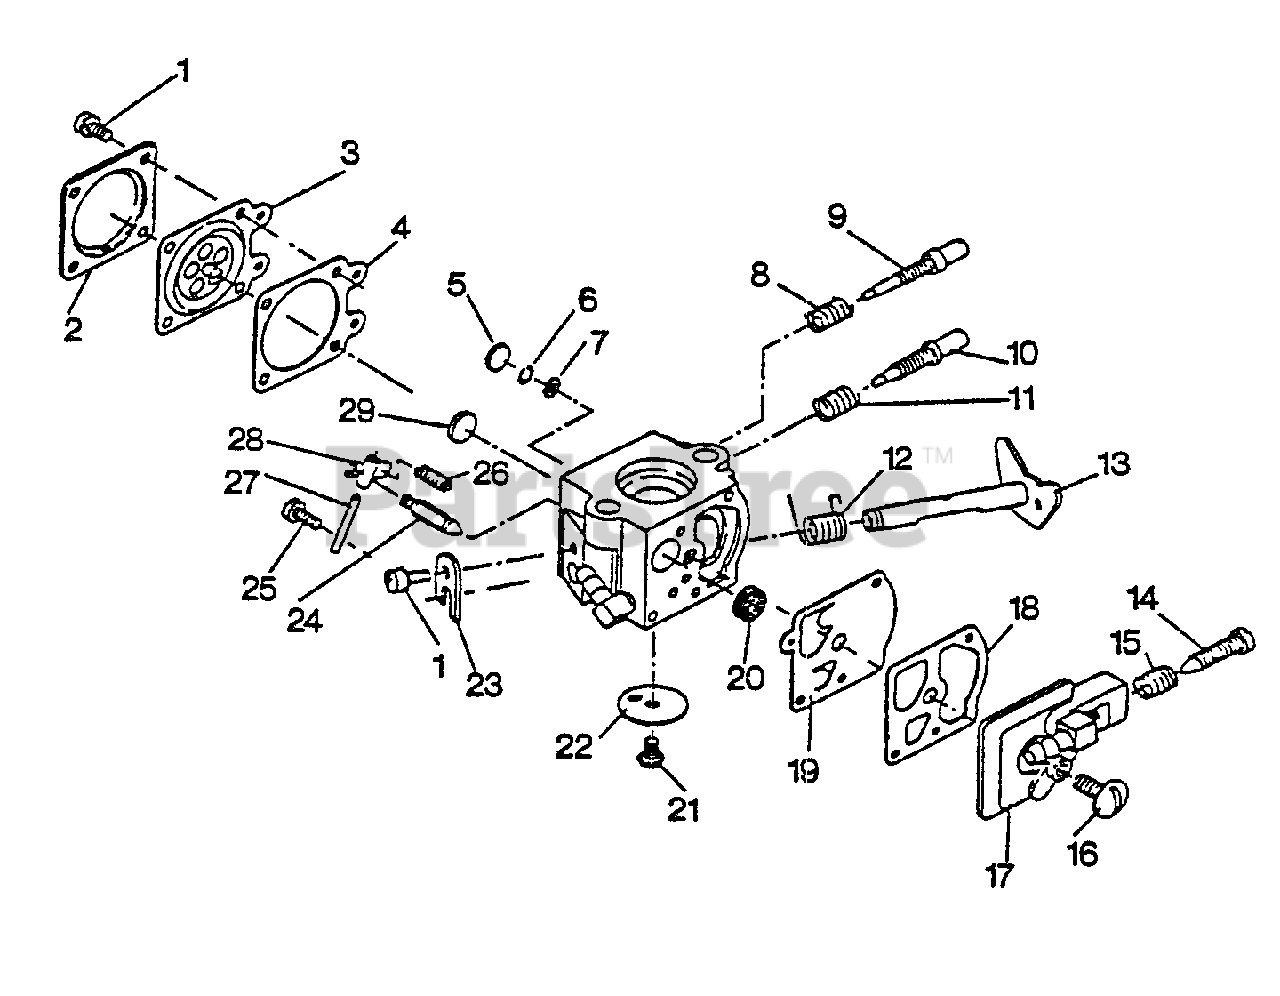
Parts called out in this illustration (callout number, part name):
1	SCREW
2	COVER, METERING
3	DIAPHRAGM, METERING
4	GASKET, METERING
5	PLUG, WELCH
6	STRAINER
7	PLUG, WELCH
8	SPRING
9	NEEDLE - HIGH SPEED
10	NEEDLE - LOW SPEED
11	SPRING
12	SPRING, THROTTLE RETURN
13	SHAFT, THROTTLE
14	SCREW, IDLE ADJUST
15	SPRING, IDLE ADJUST
16	SCREW, PUMP COVER
17	COVER, PUMP
18	GASKET, PURGE
19	DIAPHRAGM, PURGE
20	STRAINER
22	VALVE, THROTTLE
23	CLIP, THROTTLE SHAFT
24	VALVE, INLET NEEDLE
25	SCREW, METERING LEVER PIN
26	SPRING, METERING LEVER
27	PIN, METERING LEVER
28	LEVER, METERING
29	PLUG, WELCH
